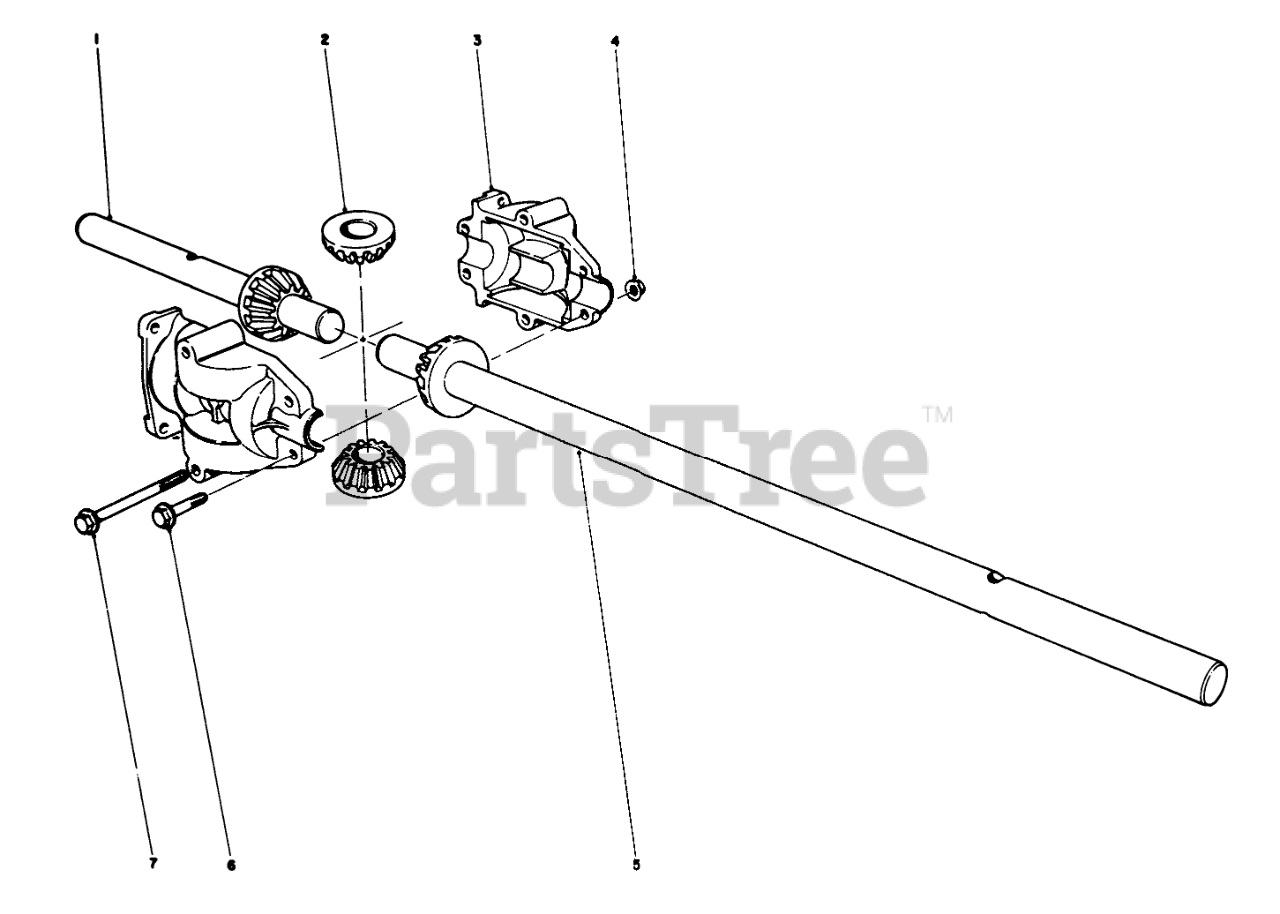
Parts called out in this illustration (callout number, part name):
1	SHORT SHAFT
2	MITER GEAR
3	DIFF HSG
4	NUT-HHF
5	LONG SHAFT
